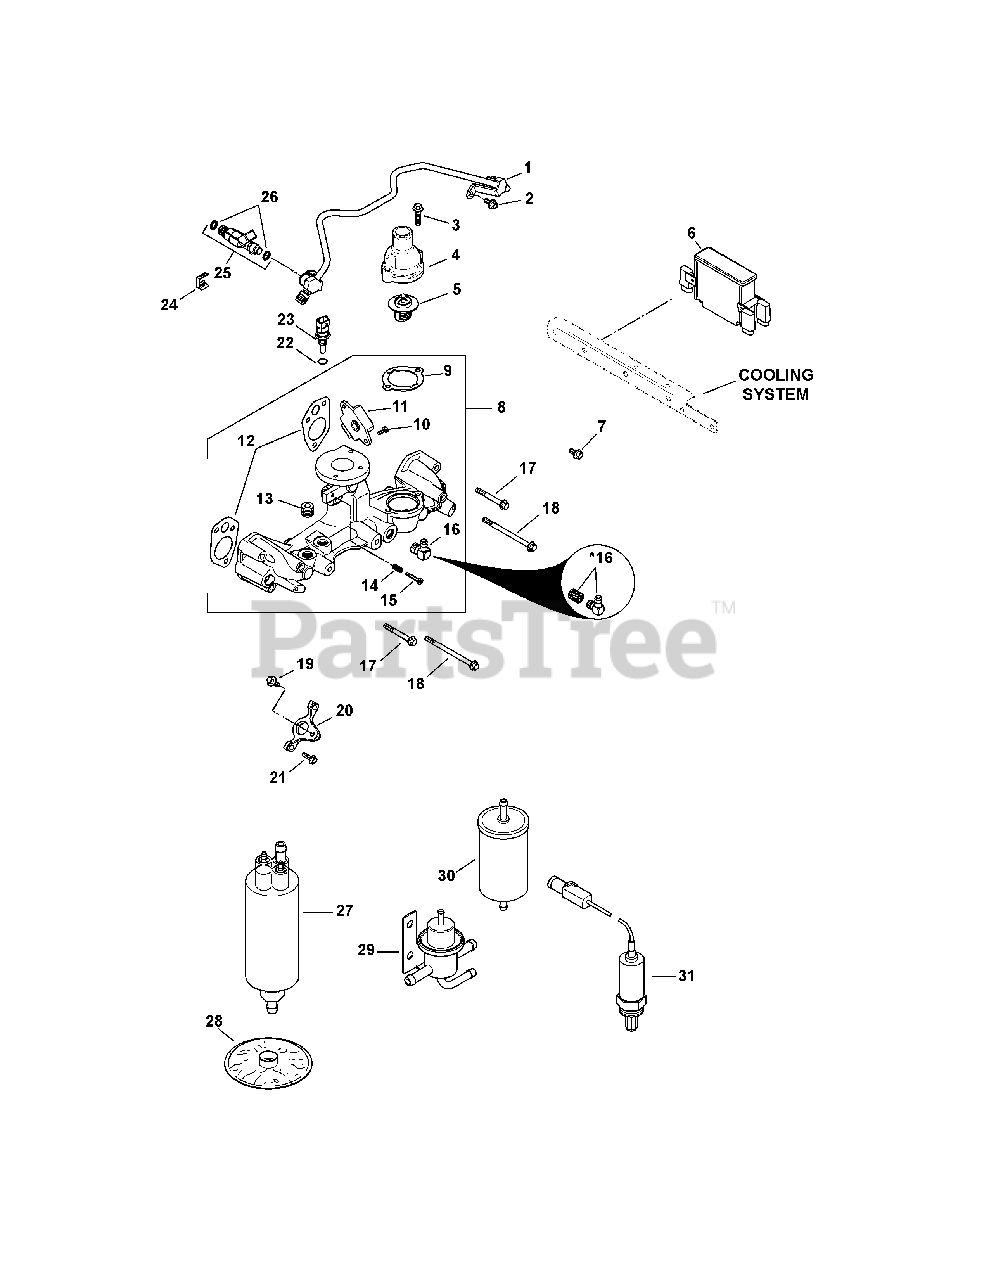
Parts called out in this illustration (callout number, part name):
2	Screw, Flg, M6 x 1.0 x 12
3	Screw, Flg, M6 x 1.0 x 25
4	Housing, Thermostat
5	Kit, Thermostat
6	Module, Engine Mngmnt. (ECU)
7	Screw, Flg, M6 x 1.0 x 12
8	Kit, EFI Intake Mnfld (Incl 9-15)
9	Gasket, Thermostat
10	Screw, Phl Pan, M4x0.7x12
11	Kit, Throttle Position Sensor
12	Gasket, Intake Manifold
13	Plug, Pipe Ctsk, 3/8"
14	Spring, Speed Control (Short)
15	Screw, Phl Pan M4 x 0.7 x 25
16	Connector, Hose
17	Screw, Flg M6 x 1.0 x 50
18	Screw, Flg M6 x 1.0 x 90
19	Screw, Flg Thd Frm M6x1.0x16
20	Bracket, Speed Sensor
21	Screw, Flg Thd Frm M5x0.8x16
23	Sensor, Temperature
24	Clip, Fuel Injector
25	Injector, Fuel (Includes 26)
27	Pump Ass’y, Fuel
28	Filter, Fuel Strainer
29	Regulator Ass’y, Fuel Pressure
30	Filter, Fuel, EFI High Pressure
31	Sensor, Oxygen
